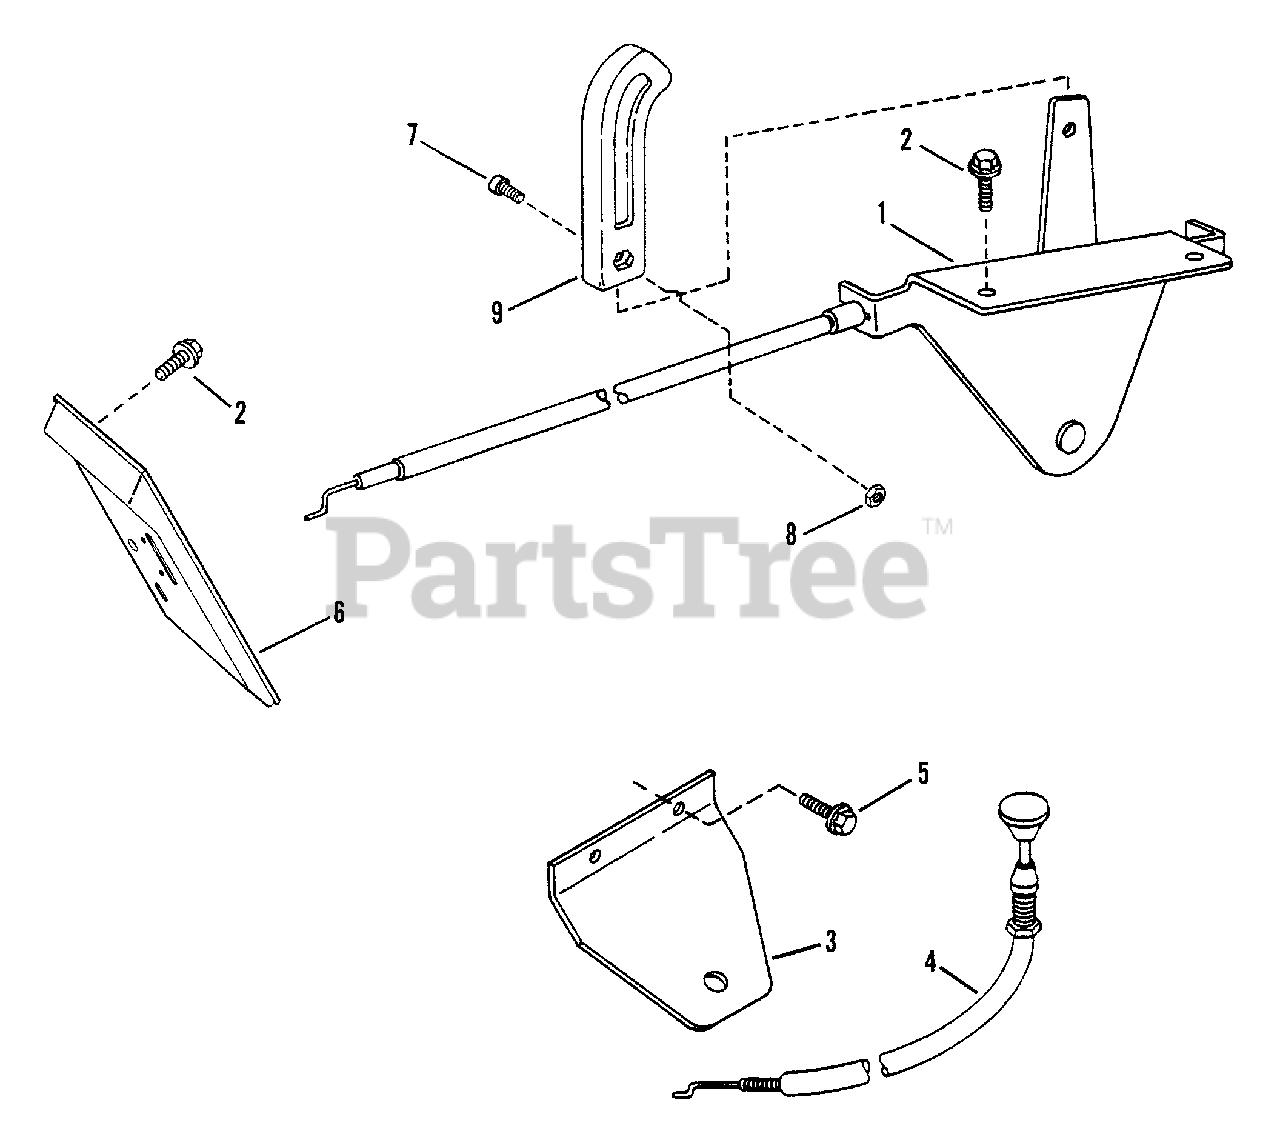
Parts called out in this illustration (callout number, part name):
1	CONTROL, Throttle
2	SCREW, #10-24 x 1/2" Hex Washer Self-Tap (Torx)
3	PLATE, Throttle Control
4	CONTROL, Choke
5	SCREW, 1/4-20 x 5/8" Self-Tapping
6	COVER, Dash Panel
7	SCREW, #8-32 x 3/8" Cross Recess Filister
8	NUT, #8-32 Hex
9	KNOB, Throttle Control
